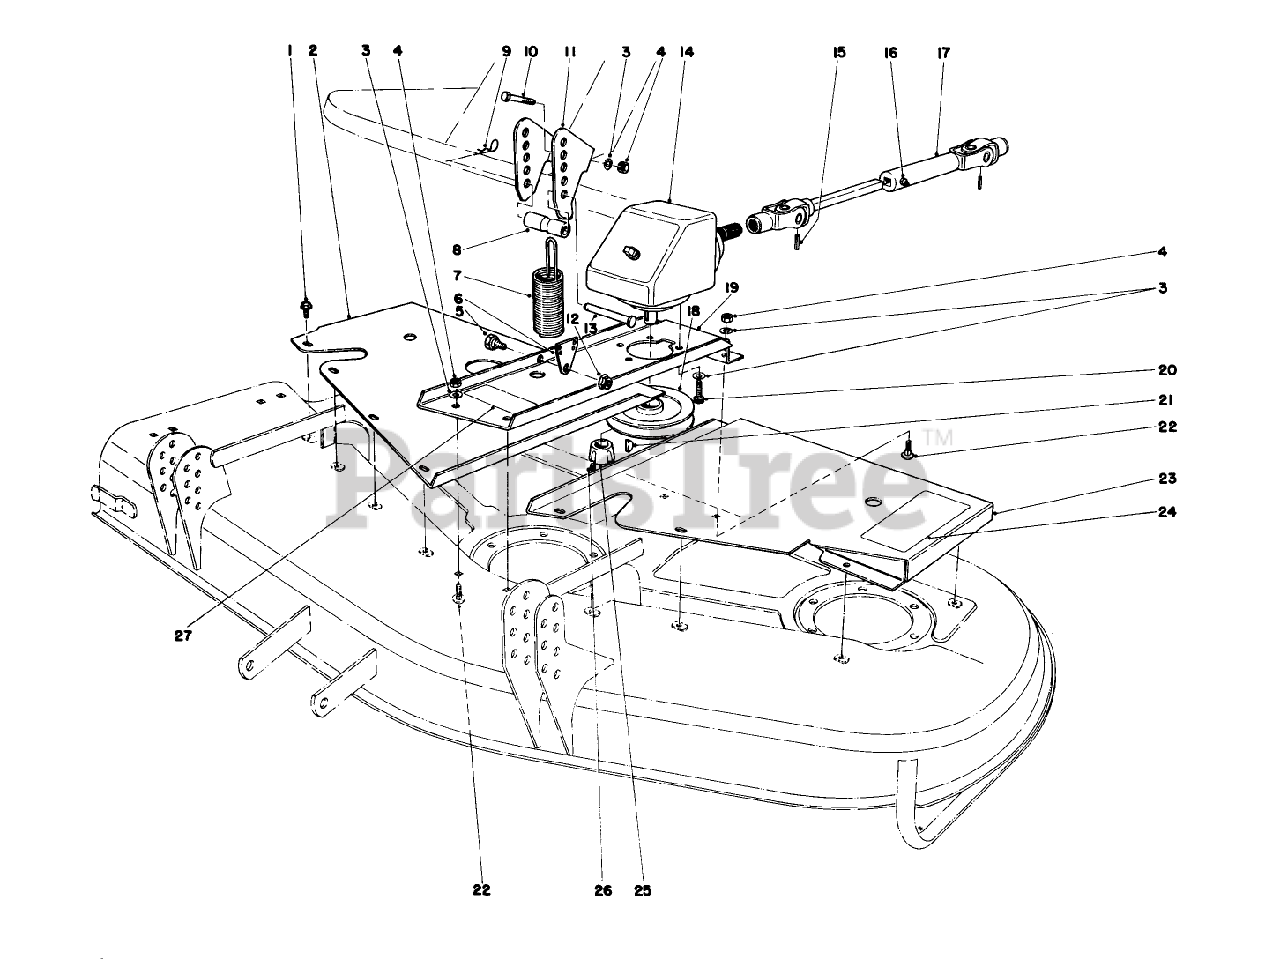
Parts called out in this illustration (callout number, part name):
1	SCREW-HHFTF
2	RH COVER WA R
3	WASHER-LOCK
4	NUT-HEX
5	BOLT-SHOULDER
6	SPRING END R
7	Spring-Extension
8	SPACER
9	PIN-HAIR
10	SCREW-HH
11	SPRING BRACKET R
12	NUT-HHF, WHIZ
13	PIN-CLEVIS
14	GEAR BOX ASM
15	PIN-ROLL
16	FITTING-GREASE
17	UNIVERSAL JOINT
18	PULLEY WA BO
19	Base-Bear Box
20	SCREW-HSH
21	KEY-WOODRUFF
22	SCREW-CARR
23	LH COVER WA R
24	DECAL
25	BUSHING-LOCK, TAPER
26	SCREW-SET, HSH
27	Decal-Caution
